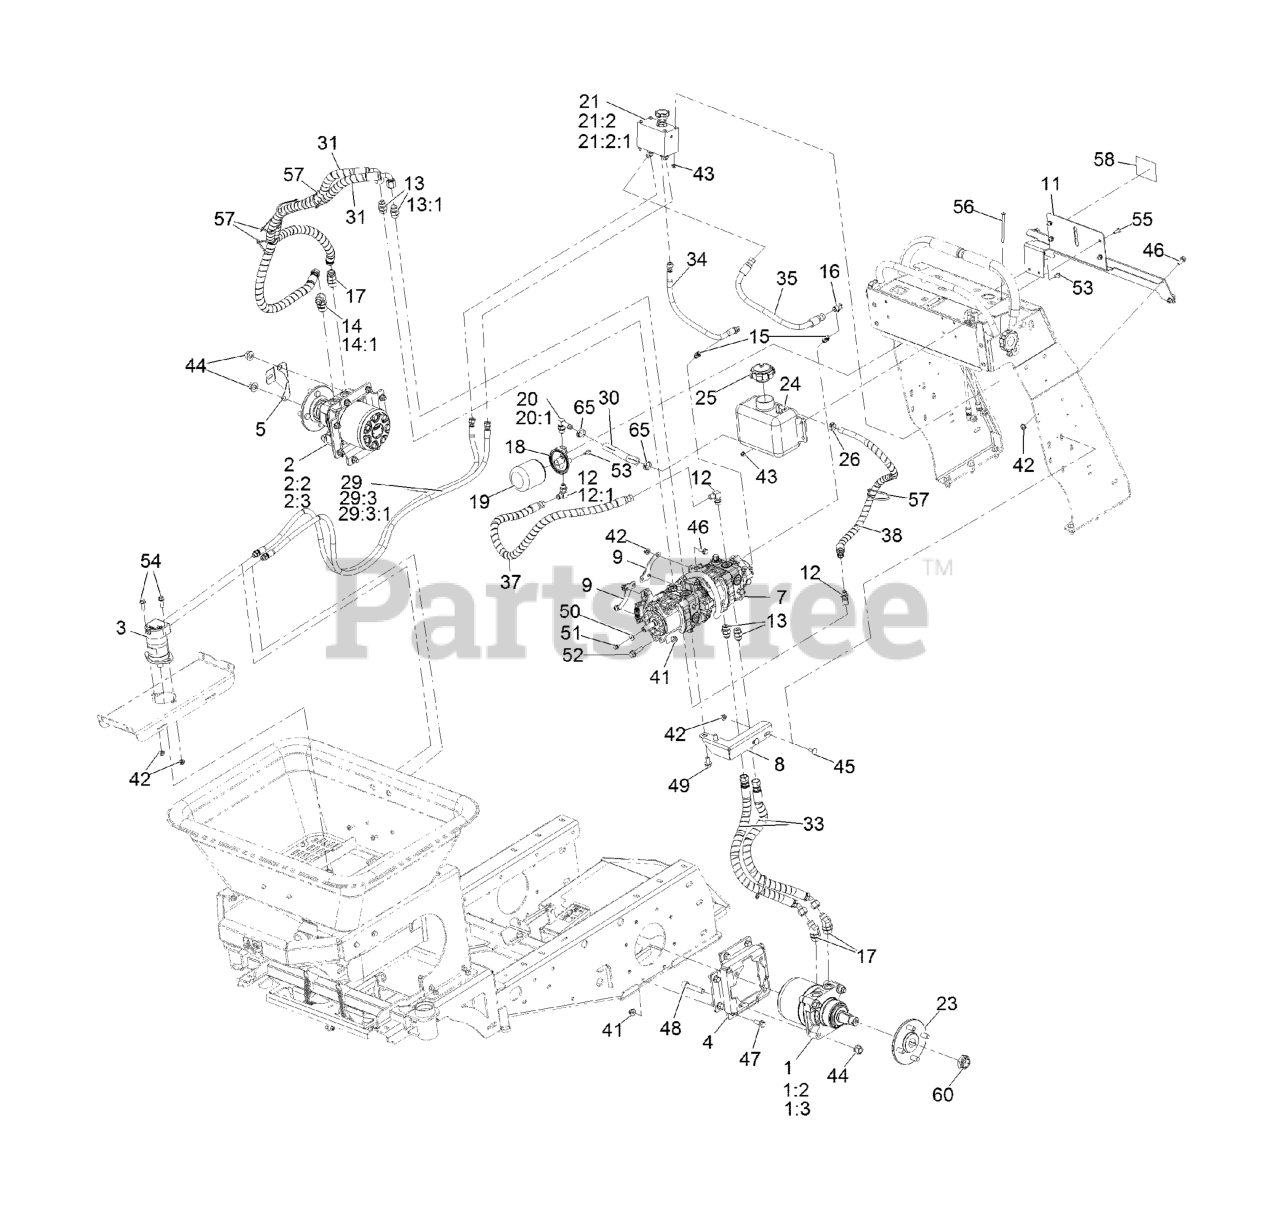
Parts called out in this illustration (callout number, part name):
1	MOTOR, LH WHEEL
1:2	KEY-WOODRUFF
1:3	SEAL KIT
2	MOTOR, RH WHEEL
2:2	KEY-WOODRUFF
2:3	SEAL KIT
3	MOTOR-HYDRAULIC, SPREADER
4	Mount-Motor, Wheel
5	BRACKET-HOPPER, SPEEDOMET
7	PUMP-TANDEM
8	Bracket-Support, Hydro Pump
9	Extension, Hydro Pump
11	Mount, Hydraulic Tank And Filter
12	FITTING-ELBOW, 90 DEG
12:1	O-RING
13	FITTING-STRAIGHT
13:1	O-RING
14	FITTING-90 DEG
14:1	O-RING
15	FITTING-STRAIGHT
16	FITTING-90 SWIVEL
17	FITTING-ELBOW, 45 DEG
18	HEAD-FILTER
19	FILTER-HYDRAULIC
20	FITTING-ELBOW, 90
20:1	O-RING
21	MANIFOLD-HOPPER, W/OUT RE
21:2	FITTING-ELBOW, 45 DEG
21:2:1	O-RING
23	HUB-WHEEL
24	TANK-HYDRAULIC, PLASTIC
25	Cap-Vented
26	CLAMP-OETIKER, 167
29	HOSE ASM, HYD HP
29:3	Fitting-Straight, Rigid
29:3:1	O-RING
30	HOSE-HYDRAULIC
31	HOSE ASM, HYD HP
33	HOSE ASM, HYD HP
34	Hose ASM, HYD HP
35	Hose ASM, HYD LP
37	Hose ASM, HYD LP
38	Hose ASM, HYD LP
41	Nut-Hex Flange
42	Nut-Hex Flange
43	Nut-Hex Flange
44	Nut-Lock 1/2-13
45	SCREW-CARR
46	SCREW-HHF
47	SCREW-HHF
48	Screw-HSH
49	SCREW-HHF
51	SCREW-HHF
52	SCREW-HHF
53	SCREW-HHF
54	SCREW-HHF
55	Screw-Hsbhf
56	Screw-HSBH
57	TIE-CABLE
58	DECAL-OIL
60	LOCKNUT
65	CLAMP-OETIKER, 167
